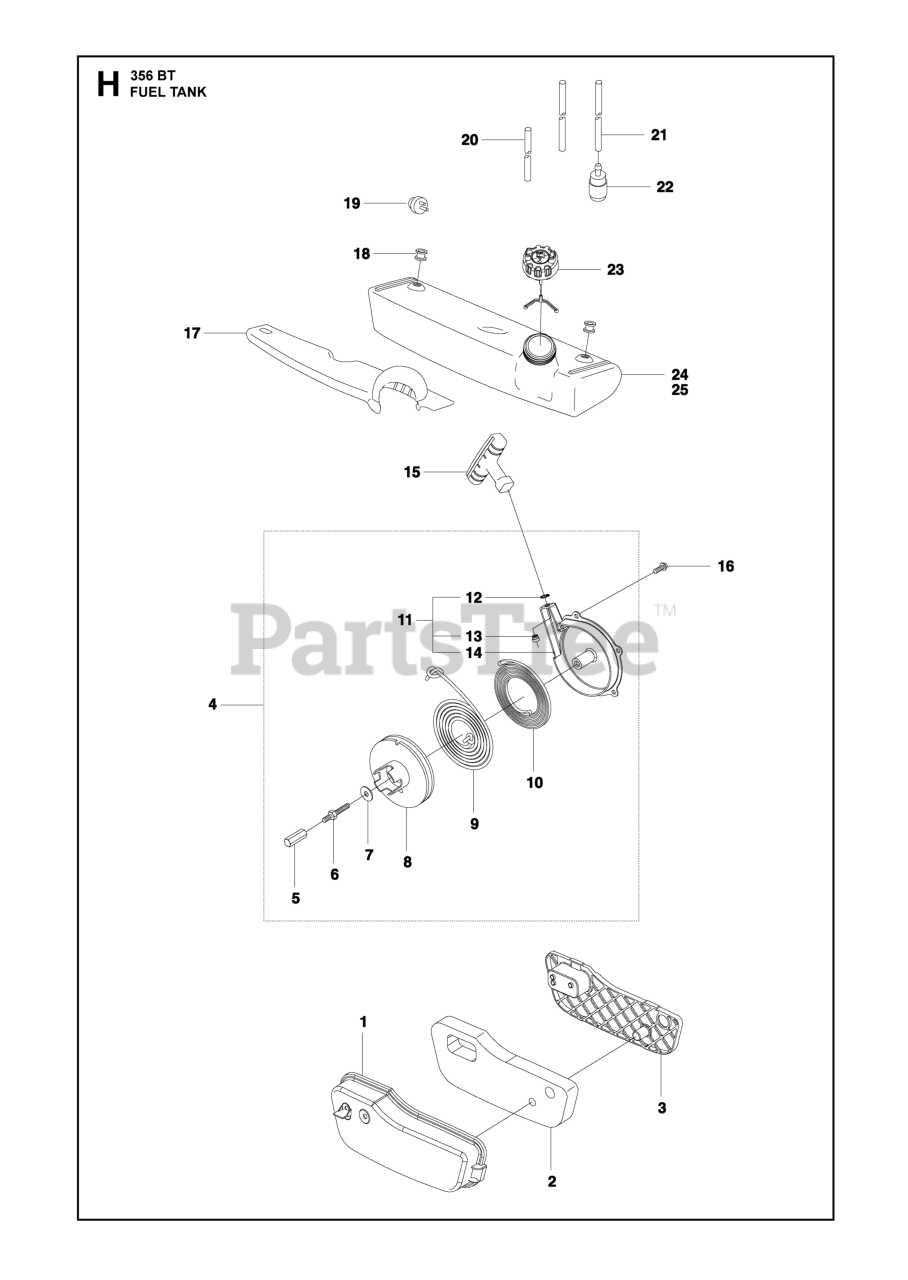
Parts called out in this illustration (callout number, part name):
2	AIR FILTER
3	NET AIR FILTER
4	STARTER DEVICE
8	STARTER PULLEY
9	STARTER ROPE
10	RECOIL SPRING
12	RETAINING RING
13	SLEEVE, STARTER HOUSING
14	STARTER DEVICE
15	STARTER HANDLE
18	FUEL TANK BUSHING
19	AIR PURGE BUBBLE
22	RP FUEL FILTER
23	FUEL CAP ASSY
23	RP TANK CAP
24	TANK UNIT
25	USA
